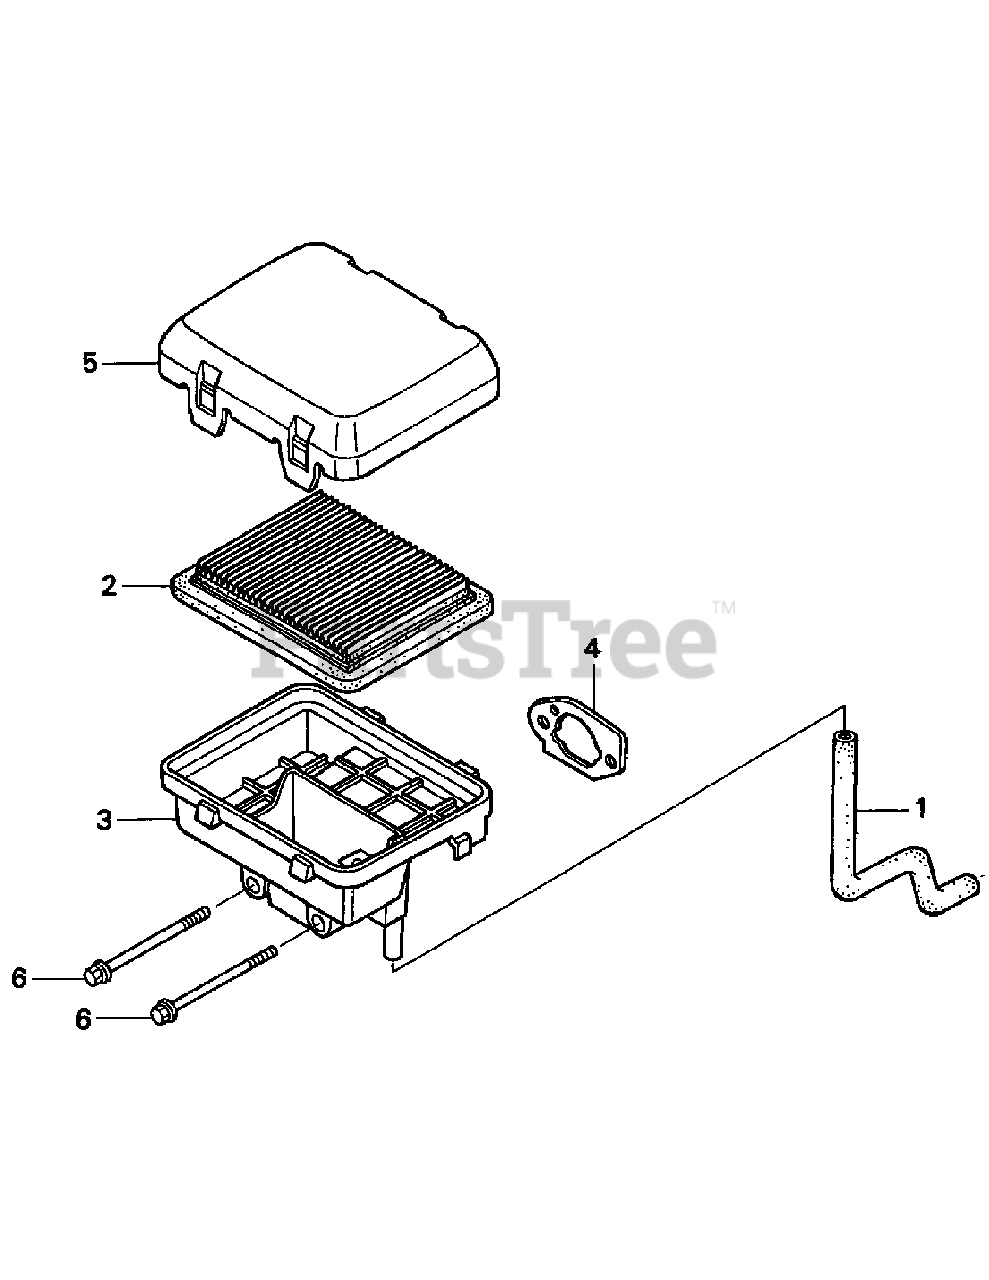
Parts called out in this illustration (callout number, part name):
1	TUBE, BREATHER
2	ELEMENT, AIR CLEANER
3	HOUSING, AIR CLEANER
4	GASKET, AIR CLEANER
5	COVER, AIR CLEANER
6	BOLT, FLANGE (6X112) (CT200)
